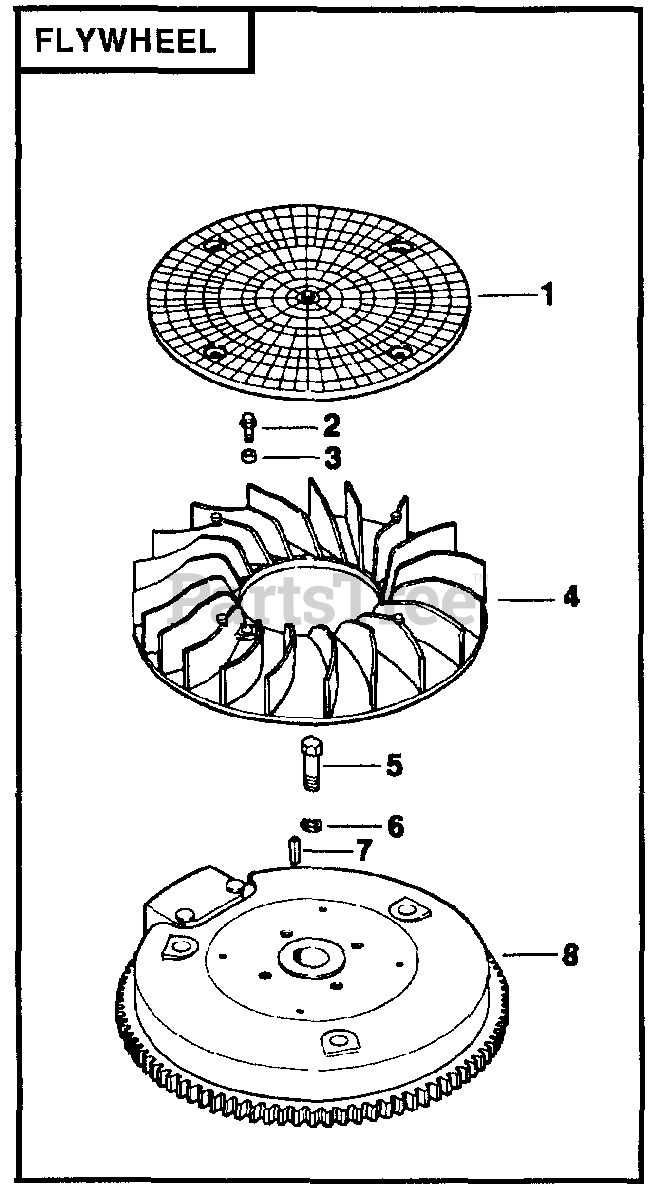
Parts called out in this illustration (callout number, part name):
2	SCREW, HEX 1/4-20 X 5/8
5	SCREW, 3/8-24X1-1/4
7	KEY
